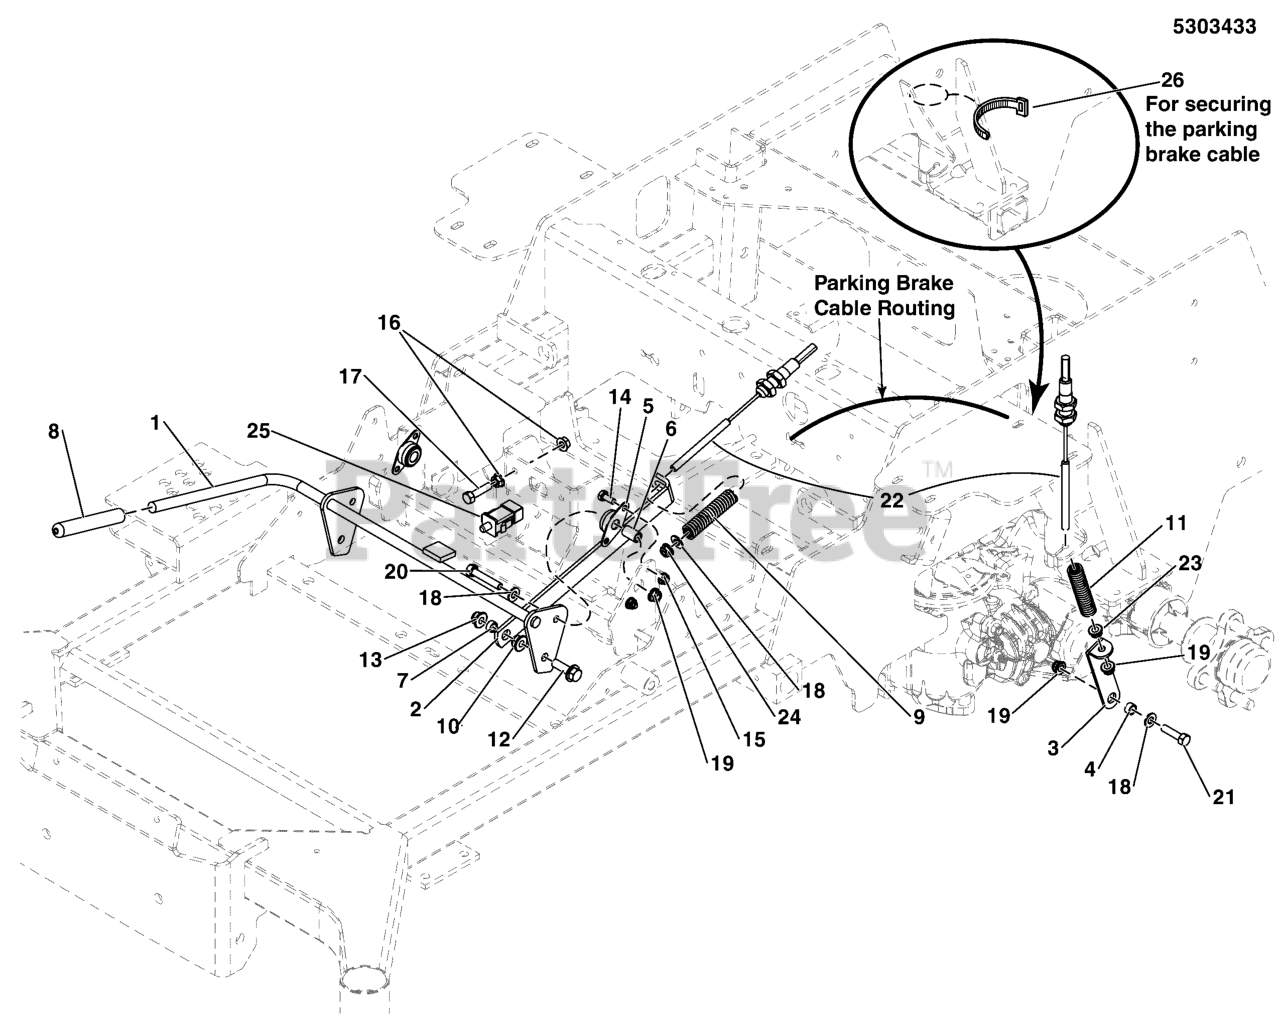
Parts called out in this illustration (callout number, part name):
1	WELD, BRAKE SHAFT, S125XT - BLK
2	LINK, BRAKE LOCK, S125XT - BLK
3	LINK, LOWER BRAKE, S125XT - BLK
4	SPACER, .33 X .50 X .25, CZ
5	BEARING, 1/2 FLANGED, PLASTIC BALL
6	SPACER, .32 X .50 X .83, CZ
7	SPACER, .38 X .50 X .27, CZ
8	GRIP, FOAM, .475 X 4.35 X .095
9	SPRING-COMP, .496ID X 3.00LG X .112WR
10	NUT, 3/8-16 HEX SERRATED FLANGE
11	SPRING-COMP, .600ID X 5.50LG X .080WR
12	BOLT, 3/8-16 X 1-1/2, FLANGE, GD 5, CZ
13	NUT, 3/8-16 HEX NYLOCK FLANGE
14	HHCS, 1/4-20 X 0.625, GR5, ZINC/CLEAR
15	NUT, 1/4-20 HEX NYLOCK FLANGE
16	NUT, 5/16-18 HEX SERRATED FLANGE (SMALL)
17	BOLT, 5/16-18 X 1-1/4 GD5 YZ
18	WASHER, 5/16" SAE
19	NUT, 5/16-18 HEX NYLOCK FLANGE
20	BOLT, 5/16-18 X 1-3/4 GD5 YZ
21	BOLT, 5/16-18 X 1-1/8 GD5
22	CABLE, PARKING BRAKE, 31" (787.9 MM)
23	NUT, 5/16-18 HEX
24	NUT, 5/16-24 HEX NYLON LOCK
25	SEE ELECTRICAL GROUP
26	TIE, SELF-LOCKING, 12"
